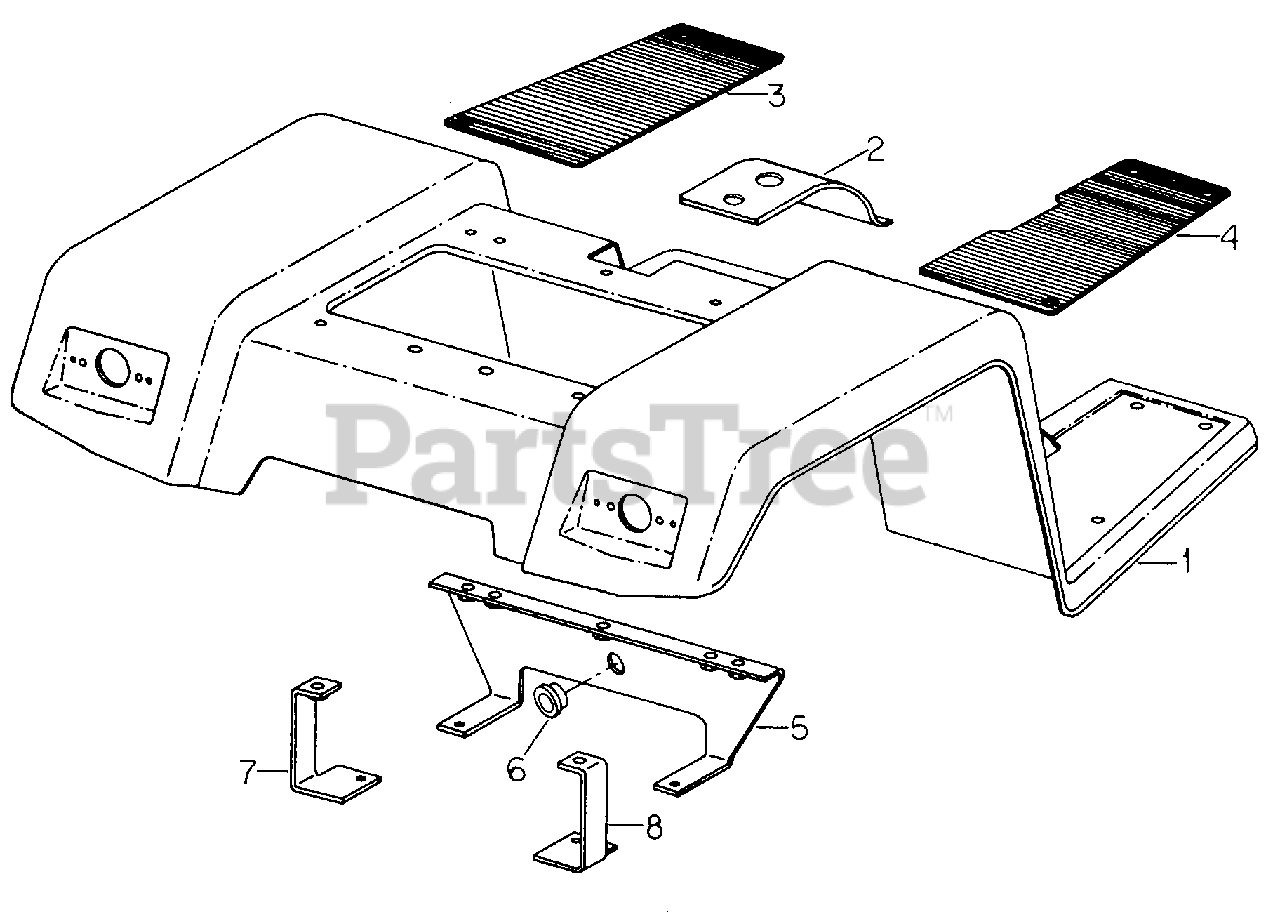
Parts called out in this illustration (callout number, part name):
2	Cover, Hydrostatic Center
3	Tread, Platform, LH
4	Tread, Platform, RH
5	Support, Fender Front
7	Support, Rear Fender, LH
8	Support, Rear Fender, RH
